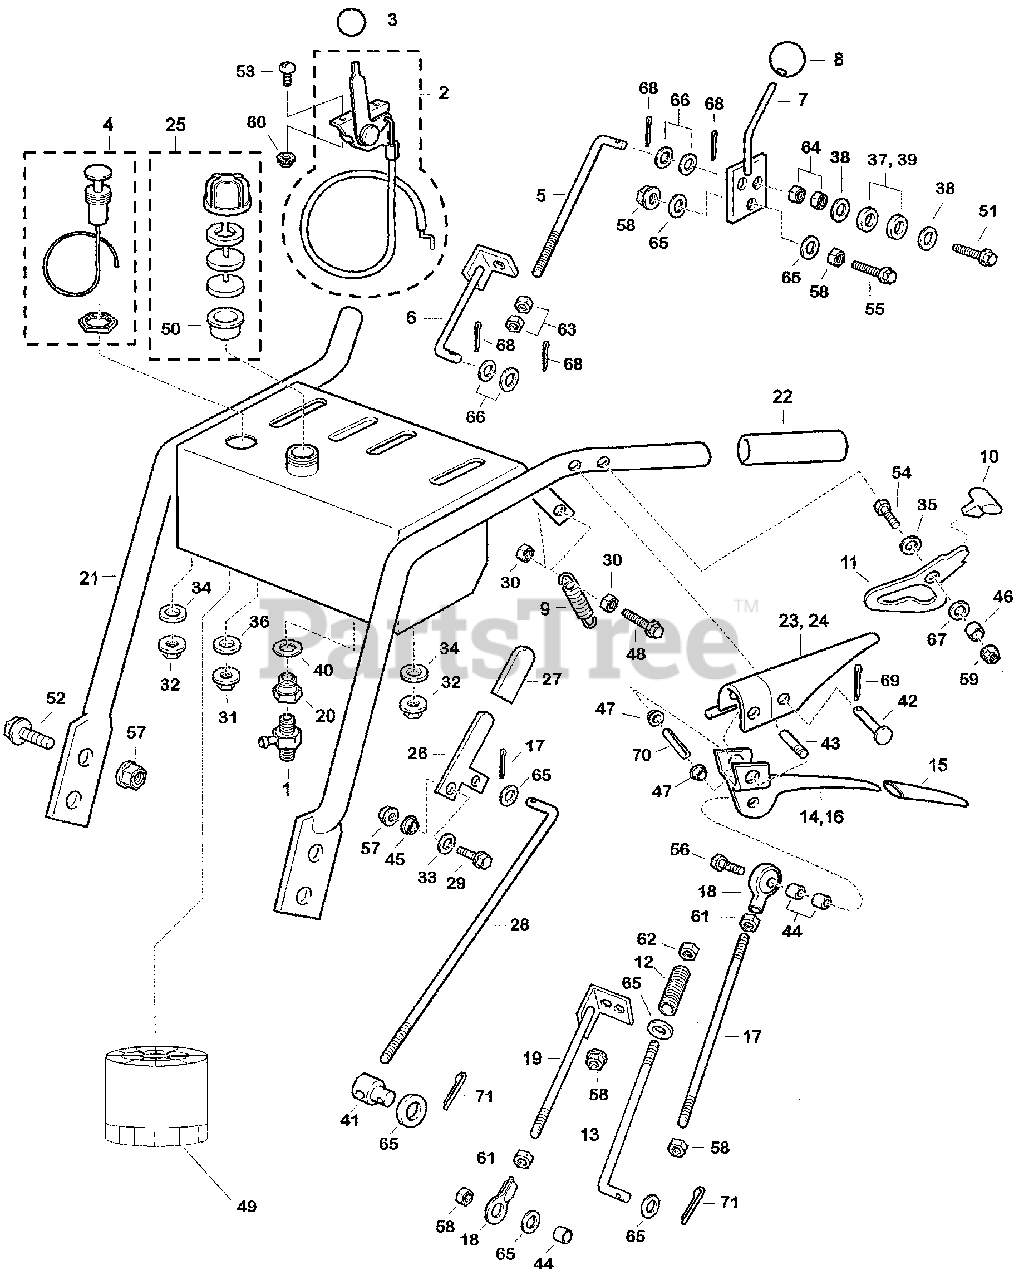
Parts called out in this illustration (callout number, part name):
1	VALVE, OIL SHUT-OFF (3/8")
2	CONTROL ASSY., THROTTLE
3	KNOB, THROTTLE
4	CHOKE ASSY., CONTROL
5	ROD A, GEARSHIFT
6	ROD B, CHANGE
7	LEVER, CHANGE
8	KNOB, CHANGE LEVER
9	SPRING, PRESENCE RETURN
10	KNOB, NEUTRAL LOCK
11	LEVER, NEUTRAL LOCK
12	SPRING, NEUTRAL
13	ROD, NEUTRAL
14	LEVER, R. TRACTION
15	GRIP, TRACTION LEVER
16	LEVER, L. TRACTION
17	ROD A, TRACTION
18	END, ROD (5/16")
19	ROD B, TRACTION
20	ADAPTER, OIL DRAIN
22	GRIP, HANDLE
23	LEVER, R. PRESENCE
24	LEVER, L. PRESENCE
25	CAP ASSY., RESERVOIR
26	LEVER, P.T.O. CLUTCH
27	GRIP, P.T.O. LEVER
28	ROD A, P.T.O.
29	BOLT A, SHOULDER
30	NUT, SELF-LOCK (5MM)
33	WASHER, BELLEVILLE (1/2")
34	WASHER A, SEAL
35	WASHER, BELLEVILLE
36	WASHER B, SEAL
37	WASHER, FRICTION THICK
38	WASHER, BELLEVILLE
39	WASHER, FRICTION THIN
40	WASHER, SEALING
41	PIN, PIVOT
42	PIN, PRESENCE LEVER
43	PIN, TRACTION LEVER
44	COLLAR, BEARING
45	BUSHING, SNAP
46	COLLAR C, SPACER
47	BUSHING, LEVER
48	BOLT, HEX. (5X25)
49	FILTER, HYDRAULIC
